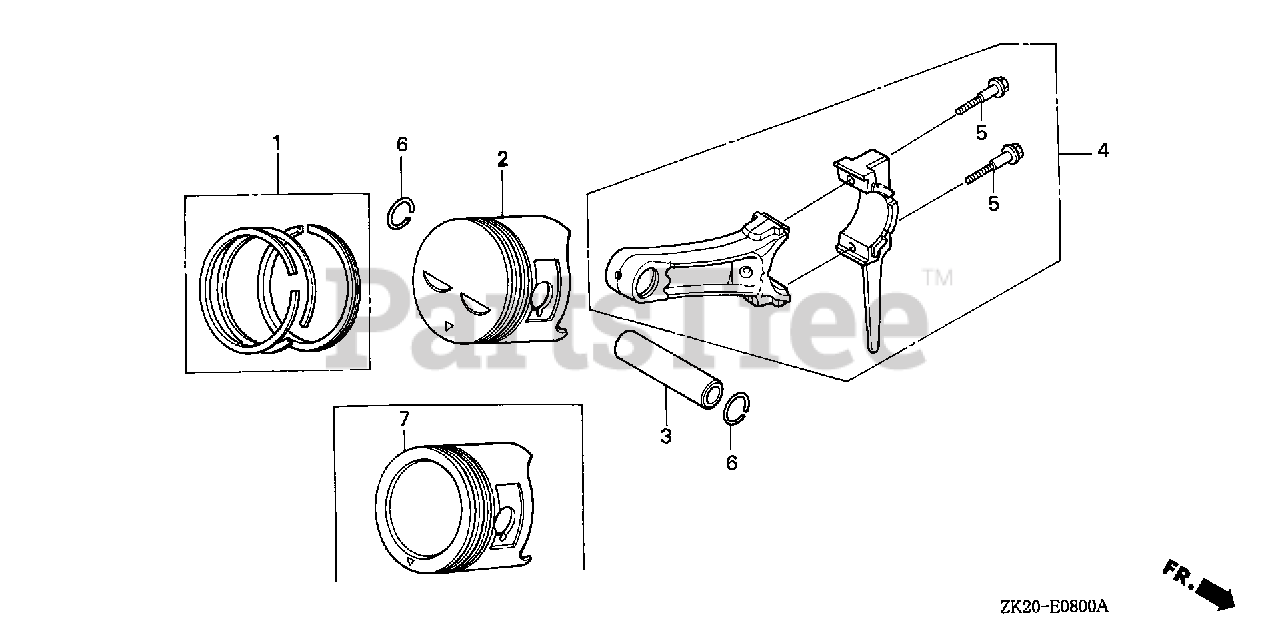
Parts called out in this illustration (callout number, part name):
1	RING SET, PISTON (STD) (NIPPON)
1	RING SET, PISTON (STD) (TEIKOKU)
1	RING SET, PISTON (0.25) (NIPPON)
1	RING SET, PISTON (0.25) (TEIKOKU)
1	RING SET, PISTON (0.50) (TEIKOKU)
1	RING SET, PISTON (0.50) (NIPPON)
1	RING SET, PISTON (0.75) (NIPPON)
1	RING SET, PISTON (0.75) (TEIKOKU)
2	PISTON (STD)
2	PISTON (0.25)
2	PISTON (0.50)
2	PISTON (0.75)
3	PIN, PISTON
4	ROD ASSY., CONNECTING (STD)
4	ROD ASSY., CONNECTING (0.25 LOWER SIZE)
5	BOLT, CONNECTING ROD
6	CLIP, PISTON PIN (18MM)
